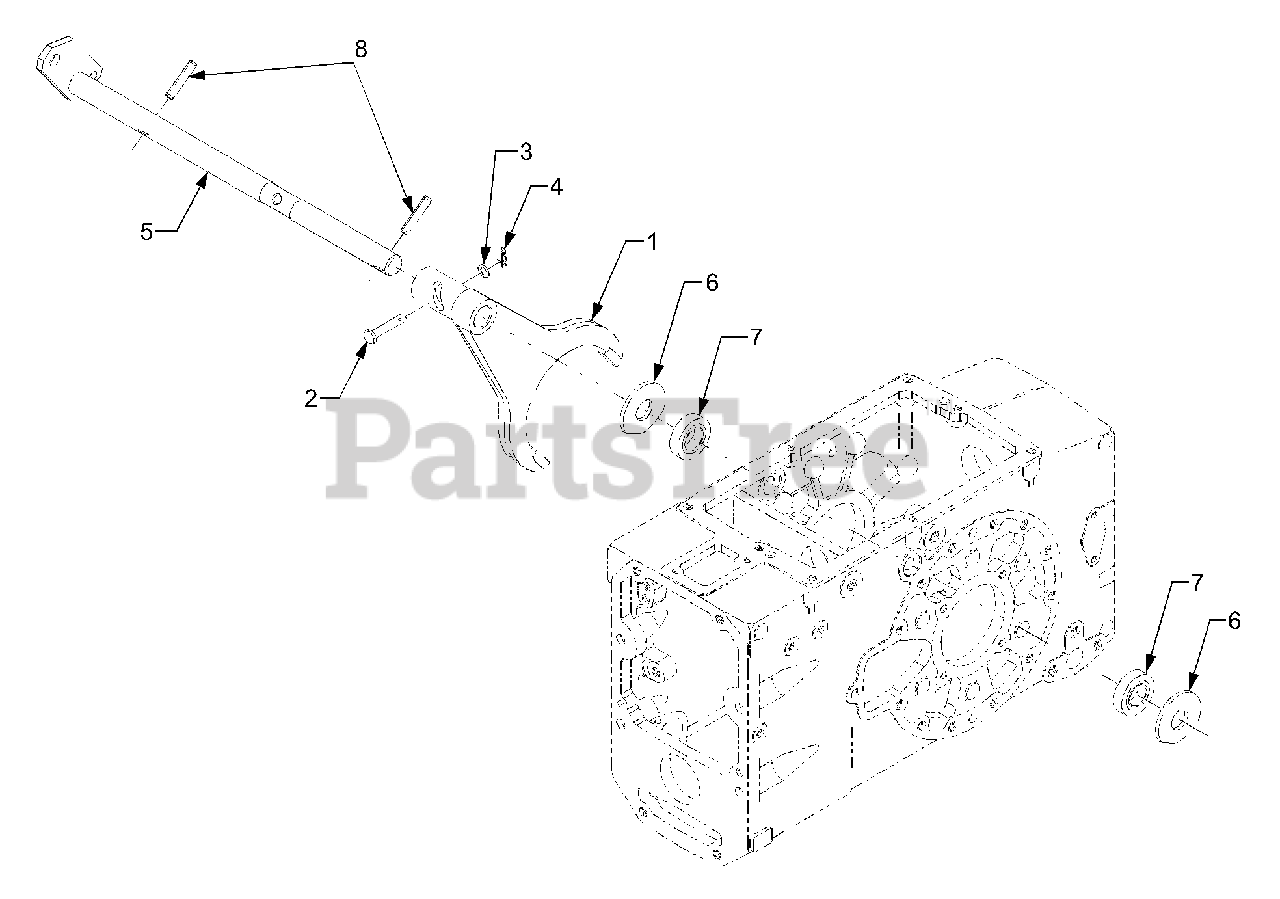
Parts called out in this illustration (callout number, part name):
1	Fork, Differential Lock
3	Washer, Plain
5	Shaft, Differential Lock Fork
